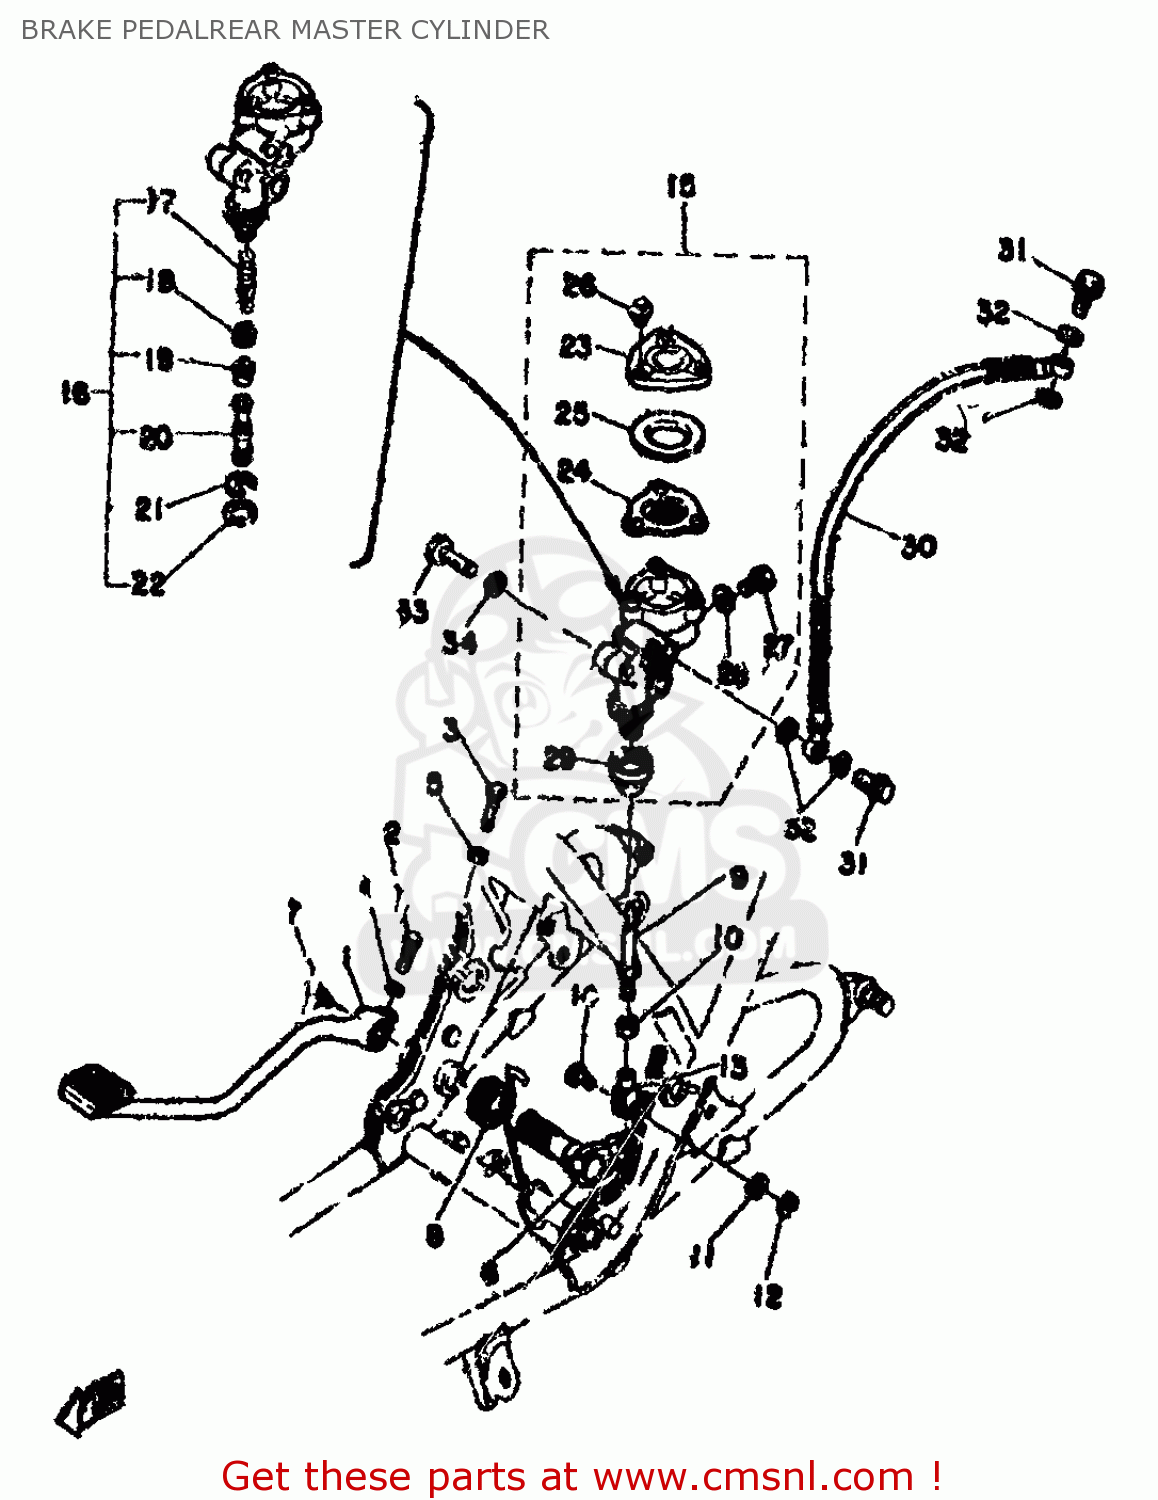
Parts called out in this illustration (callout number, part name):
1	PEDAL, BRAKE
2	BOLT (535 MASTER CYLINDER)
3	SCREW 341272170000
4	WASHER, SPRING
5	NUT, HEXAGON (371 447)
6	SHAFT,BRAKE PEDAL
7	SCREW, OVAL (6X4)
8	SPRING,TORSION
9	ROD, BRAKE
10	NUT
11	WASHER, PLATE 1562722600
12	CIRCLIP
13	JOINT
14	PIN (1J3)
15	MASTER CYLINDER ASSY
16	CYLINDER KIT, MASTER (REAR)
23	CAP, RESERVOIR
24	DIAPHRAGM, RESERVOIR
25	BUSHING, DIAPHRAGM
26	SCREW (1J3)
27	SCREW (1J3)
28	WASHER (1J3)
29	BOOTS, MASTER CYLINDER
30	HOSE,BRAKE 1
31	BOLT, UNION (481)
32	WASHER, PLATE(481)
33	BOLT (447)
34	WASHER, SPRING
